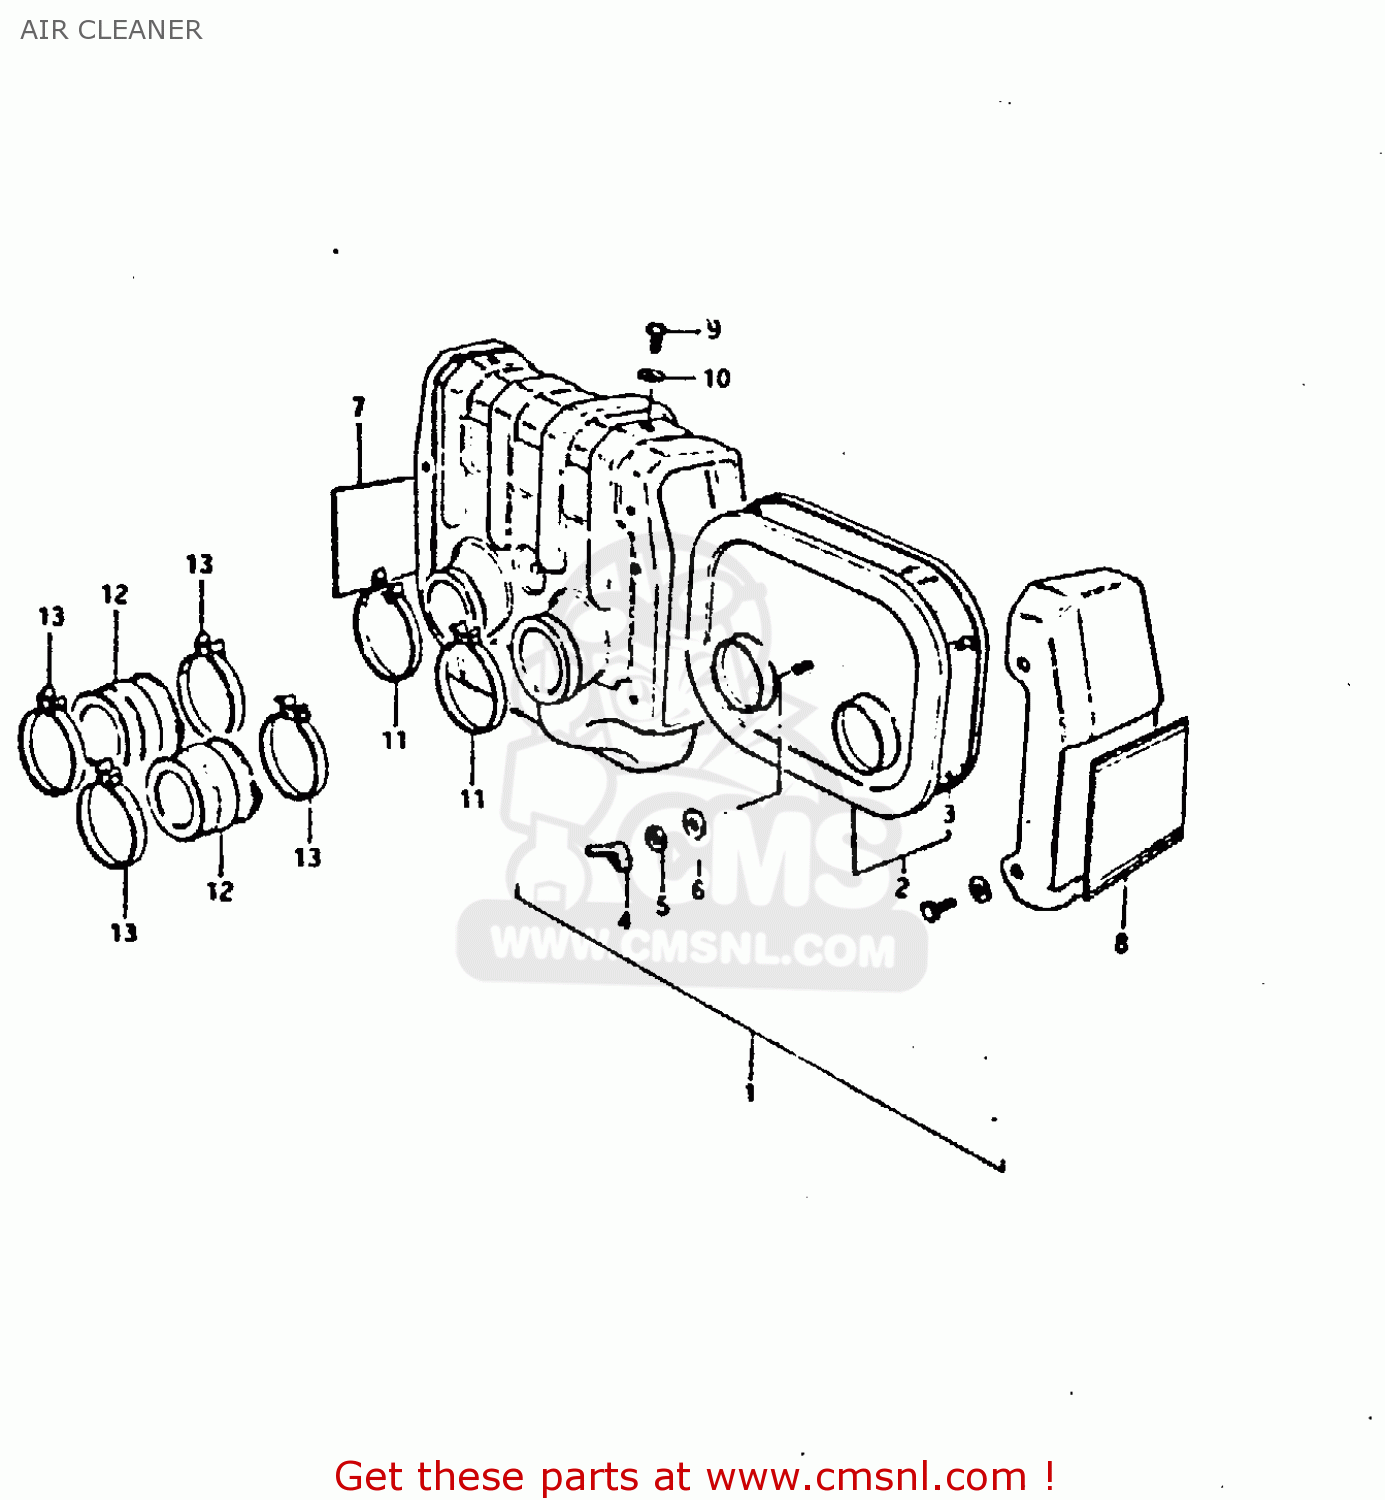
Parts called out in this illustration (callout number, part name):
1	CLEANER ASSY,AIR
2	FILTER ASSY
3	FILTER
4	NUT
5	LOCK WASHER
6	WASHER
7	TAPE, RH
8	TAPE, LH
9	SCREW
10	WASHER
11	CLAMP
12	PIPE,INTAKE
13	CLAMP
